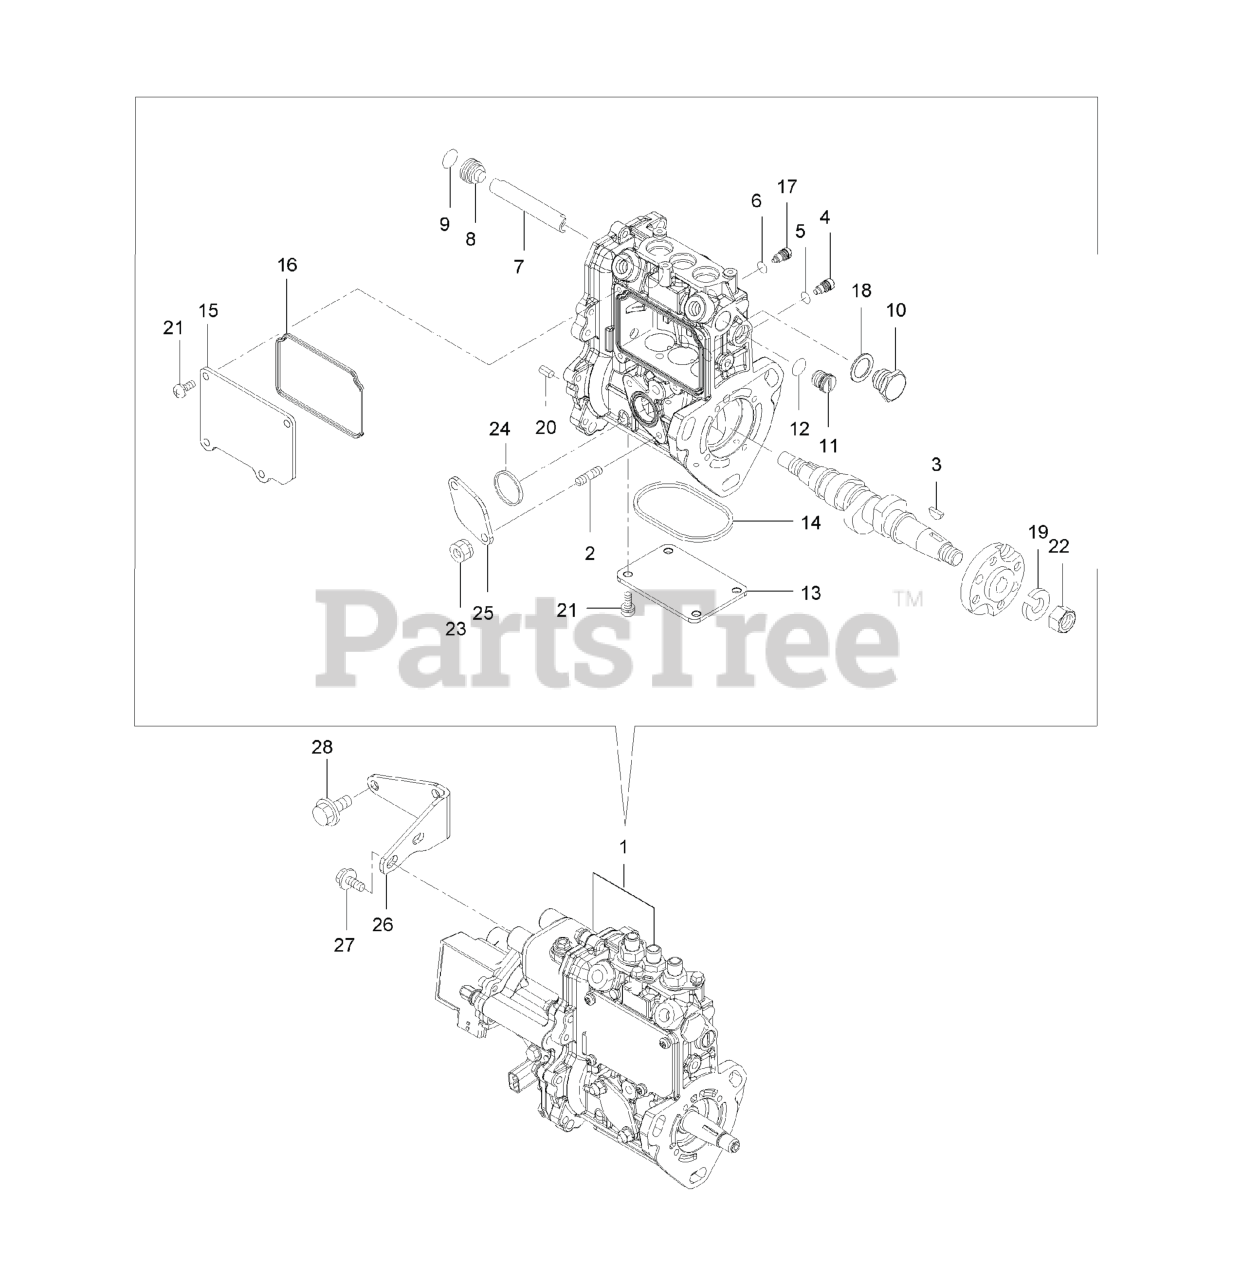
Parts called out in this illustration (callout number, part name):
1	FIE ASM
2	BOLT-STUD
3	FEATHER KEY-WOODRUFF
4	STOPPER
7	DEFLECTOR
8	PLUG-DEFLECTOR
10	PLUG-DEFLECTOR
11	PLUG-RACK
17	STOPPER-RACK
18	WASHER-SEAL
19	WASHER-SPRING
20	PIN-SPRING
25	COVER-PUMP
26	SUPPORT
